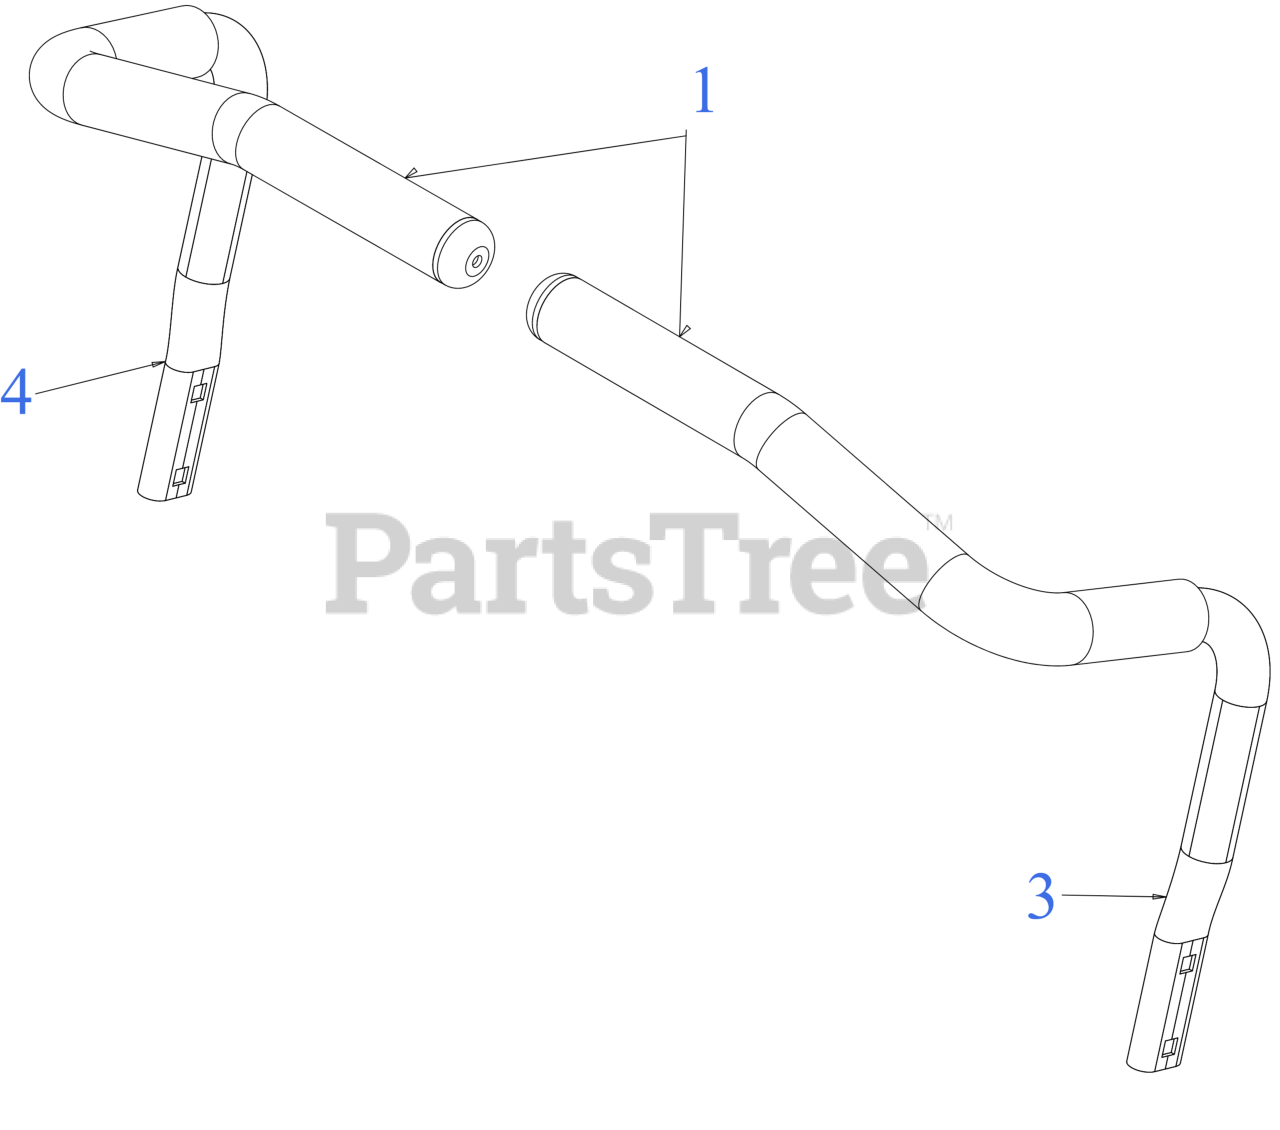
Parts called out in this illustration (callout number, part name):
1	LAPBAR GRIP
3	LAPBAR (RH) (DeWALT YELLOW)
4	LAPBAR (LH) (DeWALT YELLOW)
